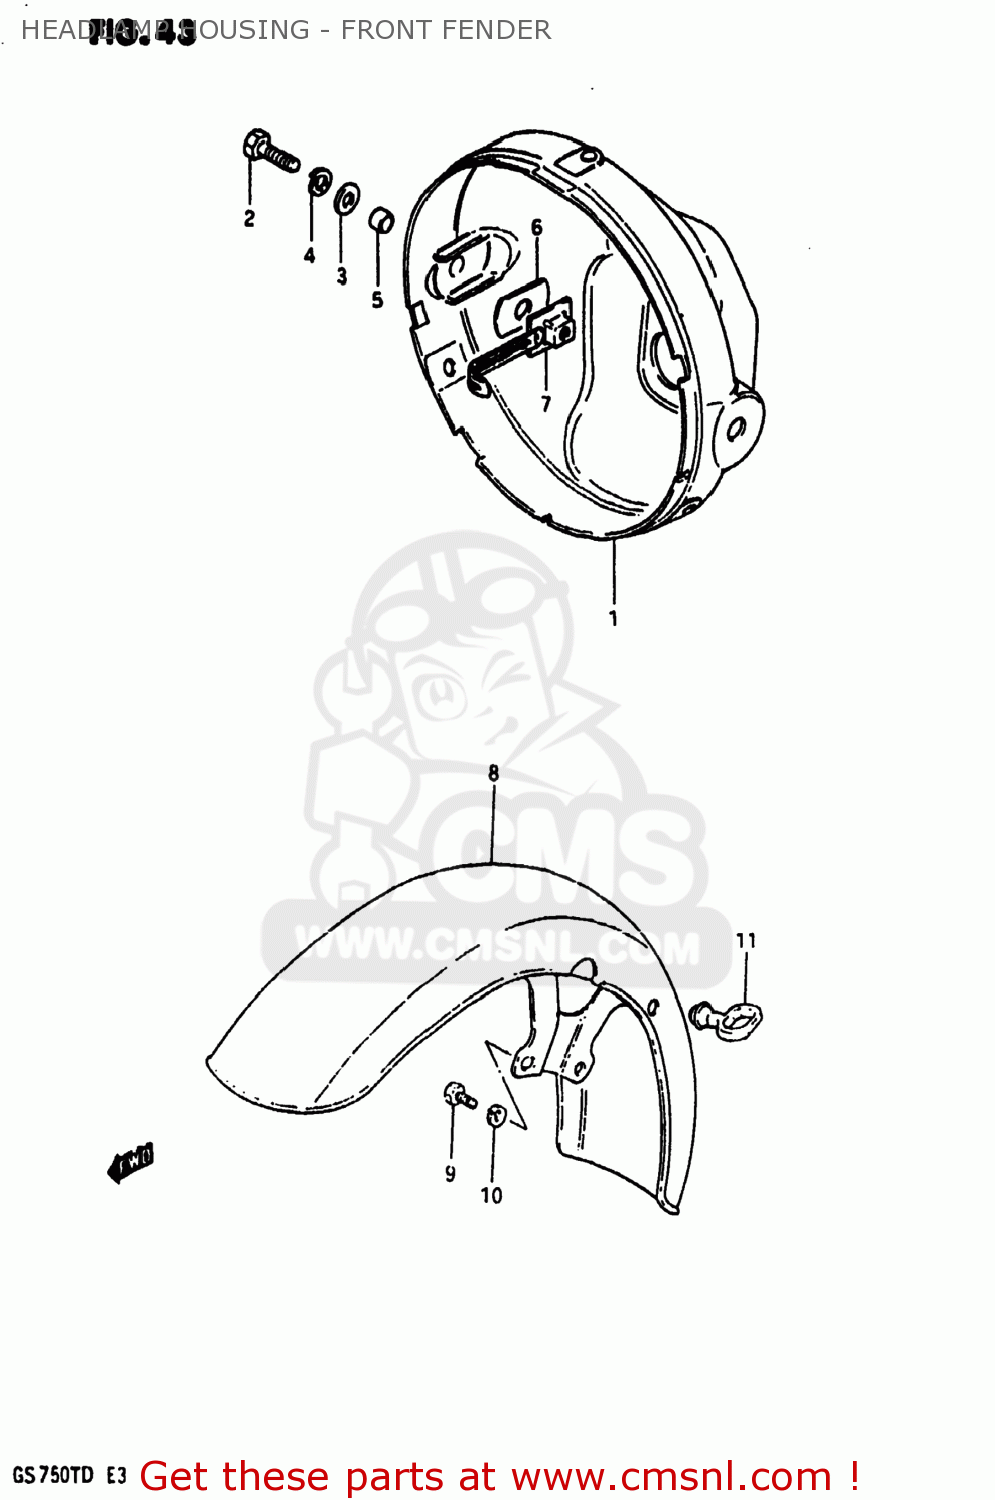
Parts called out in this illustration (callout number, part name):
1	HOUSING,HEADLAMP
2	BOLT
3	WASHER
4	LOCK WASHER
5	SPACER (8.8X12X7)
6	CUSHION
7	PLATE,HEADLAMP HOUSING
8	FENDER,FRONT
9	BOLT
10	LOCK WASHER
11	GUIDE,CABLE
